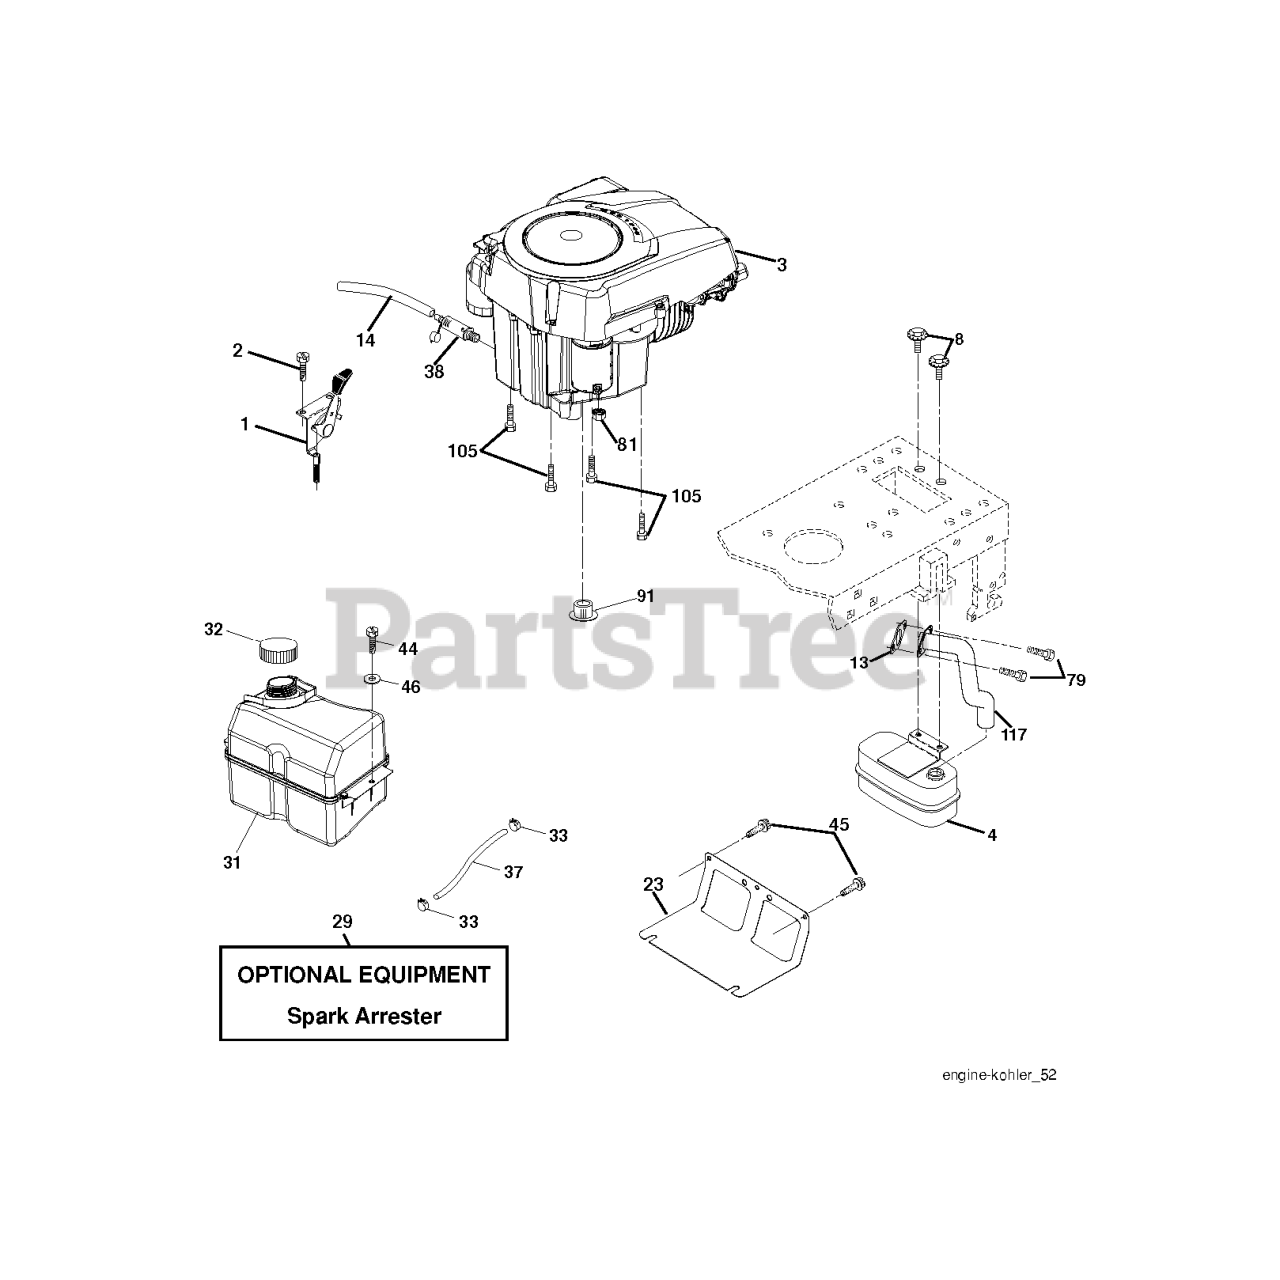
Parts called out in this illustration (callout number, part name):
1	CONTROL.TH/CK.C.
2	SCREW
4	MUFFLER.SINGLE.CYL.KOHL/B&S
8	BOLT.5/16-18UNCX3/4 W/SEMS.BLK
13	GASKET.EXHAUST.KOHLER
14	TUBE, DRAIN OIL ASM.
23	SHIELD.BROWNING.DBR.GUARD
29	KIT.SPARK ARRESTOR 794945 B&S
31	RP TANK FUEL FRT 1.5 GAL
32	FUEL CAP
33	HOSE CLAMP
37	LINE.FUEL.20
38	PLUG DRAIN OIL EASY
44	SCREW HEXWSHR 1/4-20X3/4
45	SCREW, 3/8-16X3/4
79	SCREW.SOCKET HD.5/16-1
81	NUT
91	BUSHING.1.375OD
105	SCREW 3/8-16X1
117	RP.TUBE.EXHAUST.KOHL.COURAGE
